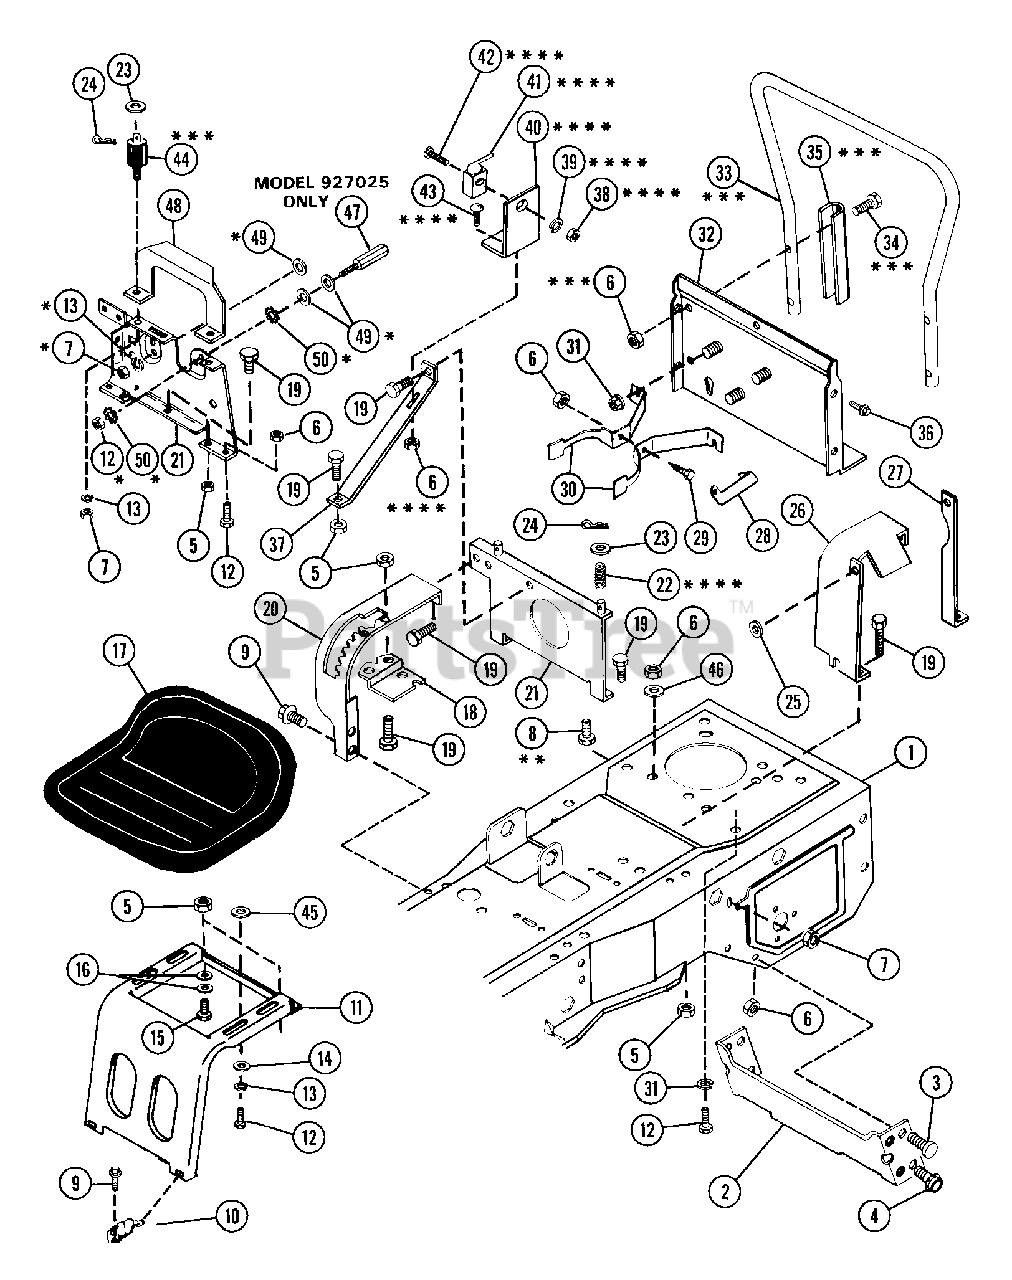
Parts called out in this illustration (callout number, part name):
1	FRAME
2	FRAME BRACE
3	BLT-HEX .31-18X.63 PL GR 2
4	SCR-TAP .312-18X1.50 HWH PL TR
5	NUT-LK-CTR .250-20 PL
6	NUT-LK .312-18 GR A PL
7	NUT-HEX .312-18
8	BLT-HEX .31-18X1.25 PL GR2
9	BLT-SERHFWH .25-20X.50 PL
11	SEAT BRACKET
12	BLT-HEX .31-18X.75 PL GR5
13	WSHR-LK .312X.097 PL HVY
14	WSHR-FL-STL .38X.875X.083 PL
15	BLT-HEX .25-20X.63 PL GR2
16	WSHR-FL-STL .406X.812X.063 PL
17	SEAT
18	BRACKET NEUTRAL SWITCH
19	BLT-HEX .25-20X.50 PL GR2
20	QUADRANT
21	SEAT LEG
22	SG-COMP
23	SPRING CUP
23	WSHR-FL-STL.312X.734X.065PL
24	PIN-HAIR INT .06X.18X.77
25	GROMMET, .31 ID
26	SHIELD
27	BRACE
28	BELT FINGER BRACE
29	BLT-HEX .31-18X.75 PL GR2
30	BELT FINGER
31	NUT-FLG. .312-18 PL
32	BACK COVER
33	TUBE
34	BLT-HEX .31-18X1.50 PL GR2
35	BRACE
36	BLT-SERHFWH .31-18X.50 PL
38	NUT-HEX 10-24 PL
39	WSHR-LK 10X.047 MED PL
40	SEAT SWITCH BRACKET
41	SWITCH INTERLOCK
42	SCR-MCH 10-24X1.00 SLRH PL
43	BLT-RDHDSQNK .312-18X.62 PL
44	ISOLATION MOUNT
45	WSHR-FL-STL .390X.750X.125 PL
46	WSHR-FL-STL .328X.875X.062 PL
47	STUD SPACER
48	ENGINE CLIP
49	WSHR-FL-STL .323X.625X.062 PL
50	WSHR-LK-INT .313X.030 PL
